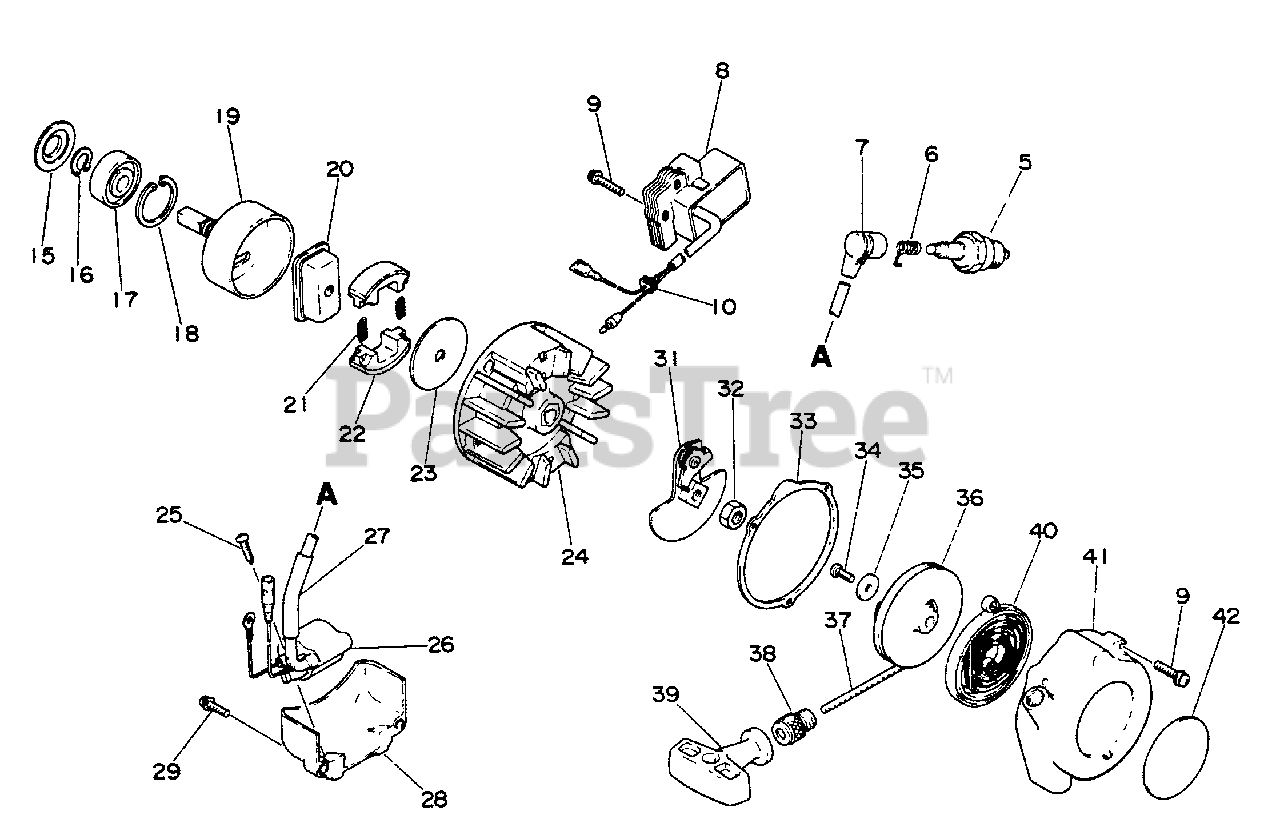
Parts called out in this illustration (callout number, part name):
5	SPARK PLUG -- CJ-8
6	TERMINAL, SPARK PLUG CAP
7	CAP, SPARK PLUG
8	COIL, IGNITION
9	SCREW - 4X20
15	RETAINER, PIPE
16	RING, RETAINING - 12
17	BEARING, BALL - 6201
18	RING, RETAINING - 32
19	DRUM, CLUTCH
20	HUB, CLUTCH
21	SPRING, CLUTCH
22	SHOE, CLUTCH
23	PLATE, CLUTCH
24	FLYWHEEL
25	SCREW - 4X16 -- TAPPING
26	COIL, IGNITION
27	TUBE
28	COVER
29	SCREW - 4X14
31	STARTER PAWL ASSY
33	GASKET, STARTER
34	SCREW - 4X10
35	WASHER
36	REEL, ROPE
37	ROPE, STARTER - 3X850
38	GUIDE, ROPE
39	GRIP, STARTER
40	SPRING, REWIND
41	CASE, STARTER
42	LABEL - ECHO
